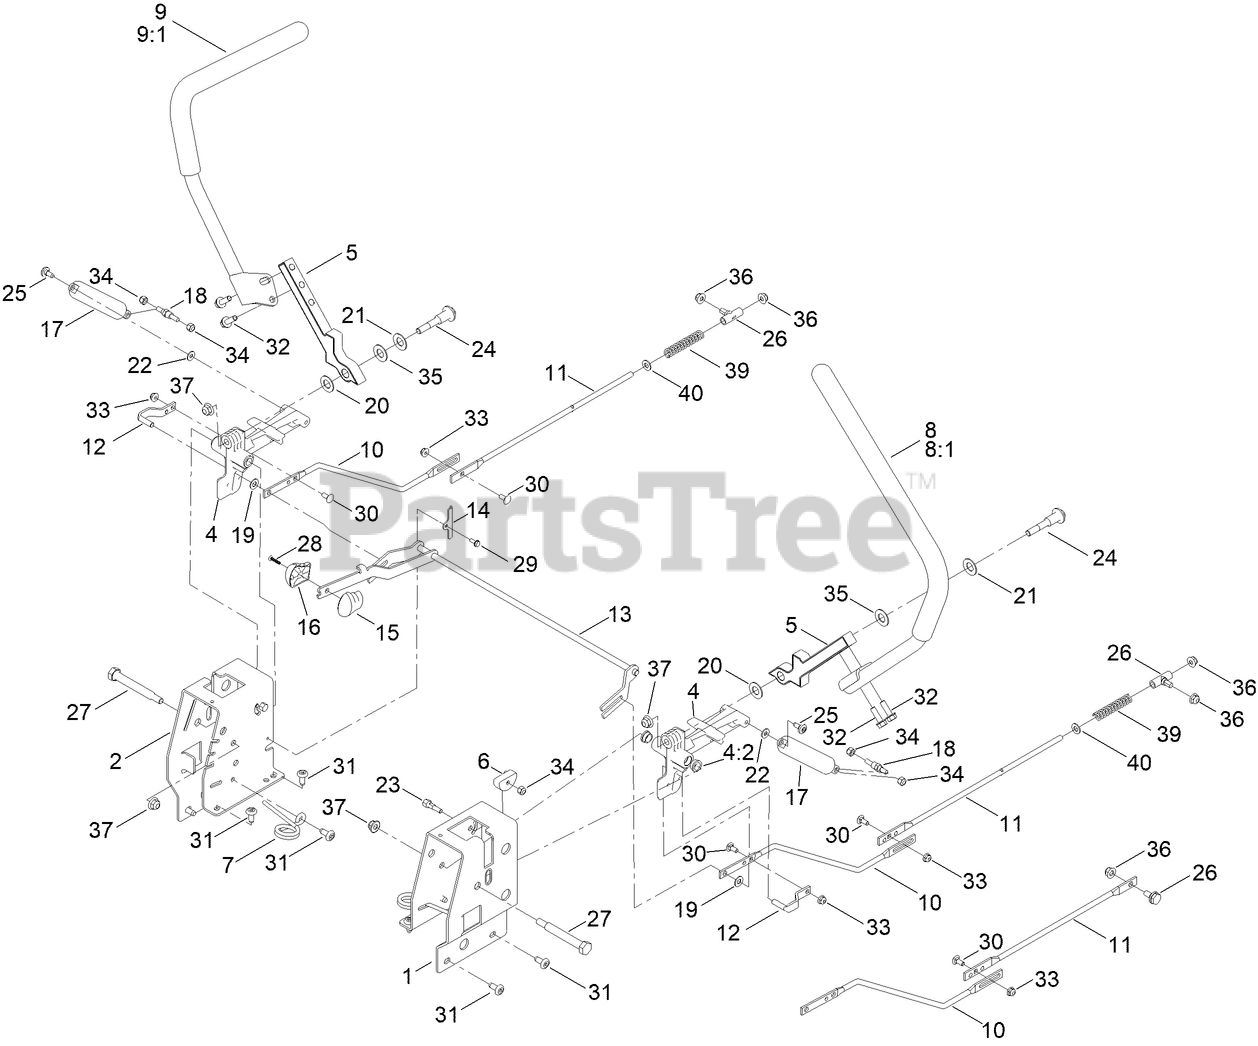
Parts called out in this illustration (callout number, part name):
1	PLATE-CONTROL BOX, LH
2	PLATE-CONTROL BOX, RH
4	ACTUATOR ARM ASM
4:2	BUSHING-FLANGE
5	ARM-CONTROL
6	ECCENTRIC
7	SPRING-TORSION
8	HANDLE-CONTROL, LH
9	HANDLE-CONTROL, RH
10	ROD-HYDRO, FRONT
11	ROD-HYDRO, REAR
12	PIN-ROD, HYDRO
13	SPEED CONTROL ASM
14	PLATE-RETAINER
15	KNOB-RH
16	KNOB-LH
17	DAMPER-NON CAVITATING
18	STUD-DAMPER
19	SPACER-NYLON
20	WASHER-NYLON
21	WASHER-BELLEVILLE
22	WASHER
23	BOLT-PIVOT, ECCENTRIC
24	BOLT-PIVOT
25	SCREW-SHOULDER
26	MOUNT-ROD, HYDRO
27	BOLT-PIVOT
28	SCREW-PPH
29	SCREW-TAPTITE
30	BOLT-CARR
32	SCREW-HHF
33	NUT-HF
34	NUT-HEX
35	WASHER
36	NUT-HF
37	NUT-HF, NI
39	SPRING-COMPRESSION
40	WASHER-PLAIN
